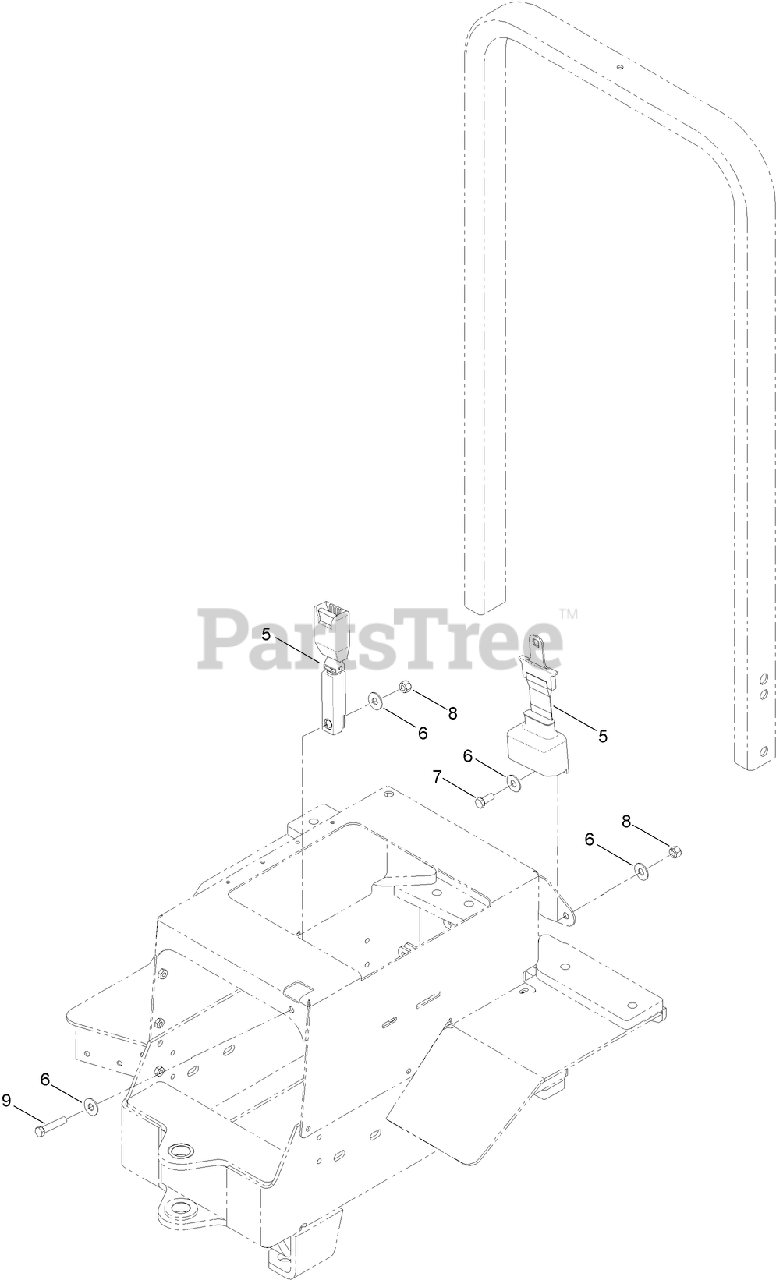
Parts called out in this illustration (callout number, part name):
5	SEAT BELT ASM
6	WASHER-FLAT
7	SCREW-HH
8	NUT-LOCK
9	SCREW-HH
